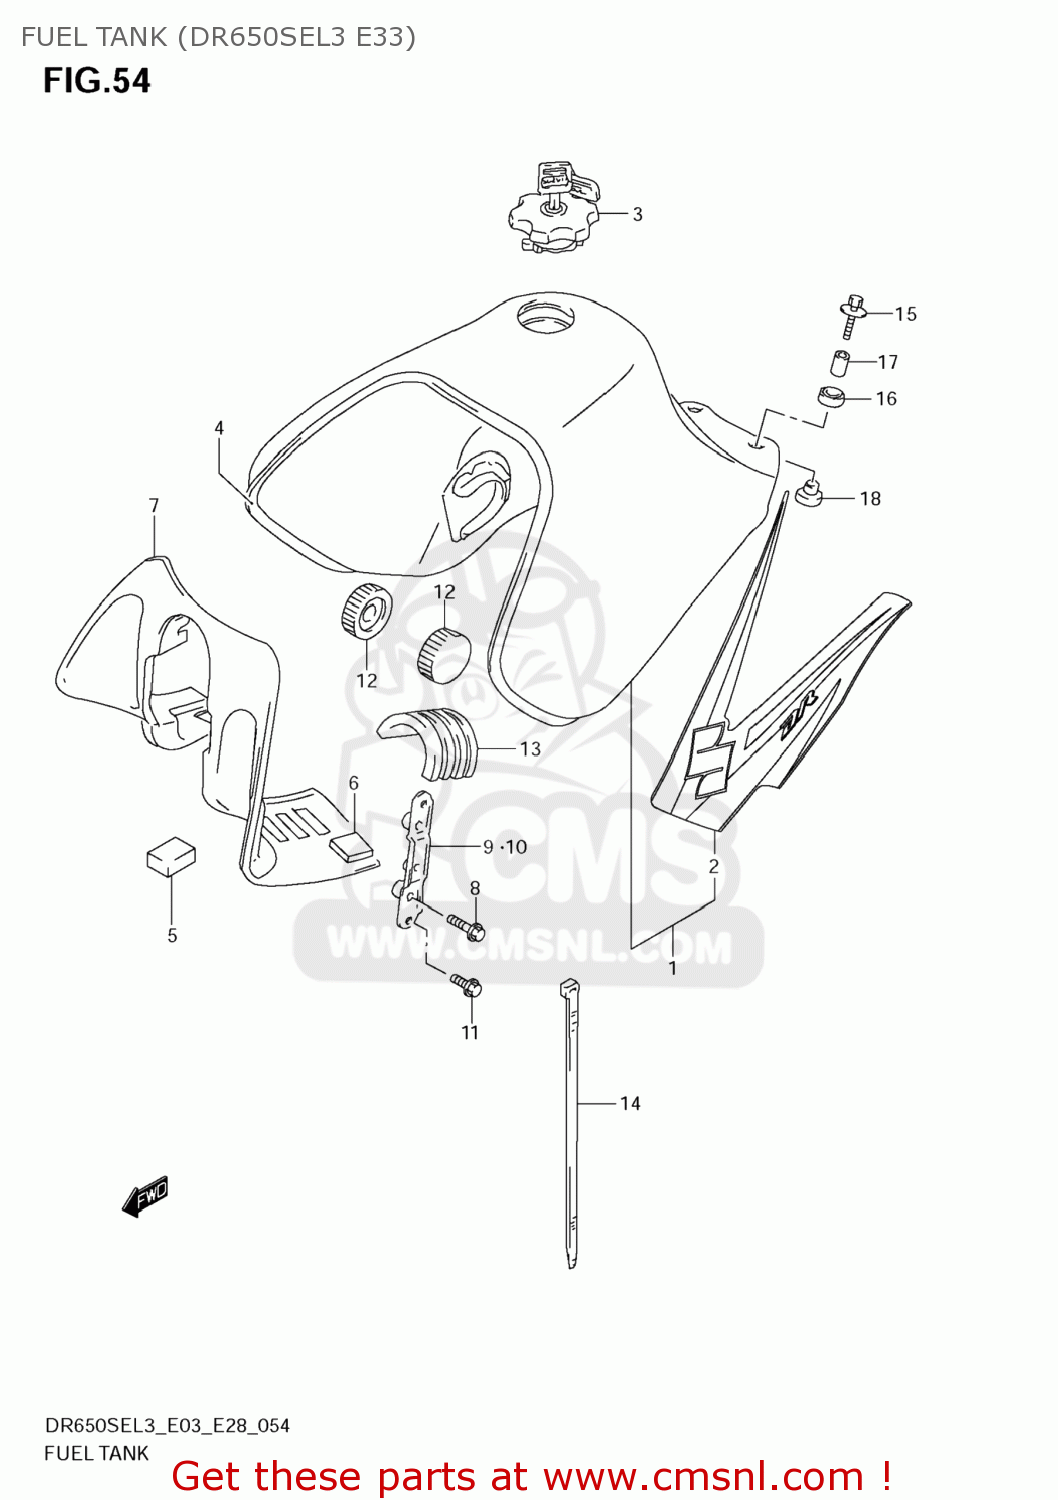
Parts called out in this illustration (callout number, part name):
1	TANK ASSY,FUEL(GRAY)
2	TAPE SET,FUEL TANK
3	CAP SET,FUEL TANK
4	MOLDING,FUEL TANK
5	CUSHION,HEAD LAMP HOUSING
6	CUSHION,OIL TANK UPR
7	COVER,FUEL TANK FR
8	BOLT(6X12)
9	BRACKET,FUEL TANK COVER,R
10	BRACKET,FUEL TANK COVER,L
11	BOLT
12	CUSHION,FUEL TANK FR
13	CUSHION,FUEL TANK UPR
14	CLAMP(L:250)
15	BOLT(6X30)
16	CUSHION
17	SPACER(6.5X9X18)
18	CUSHION
